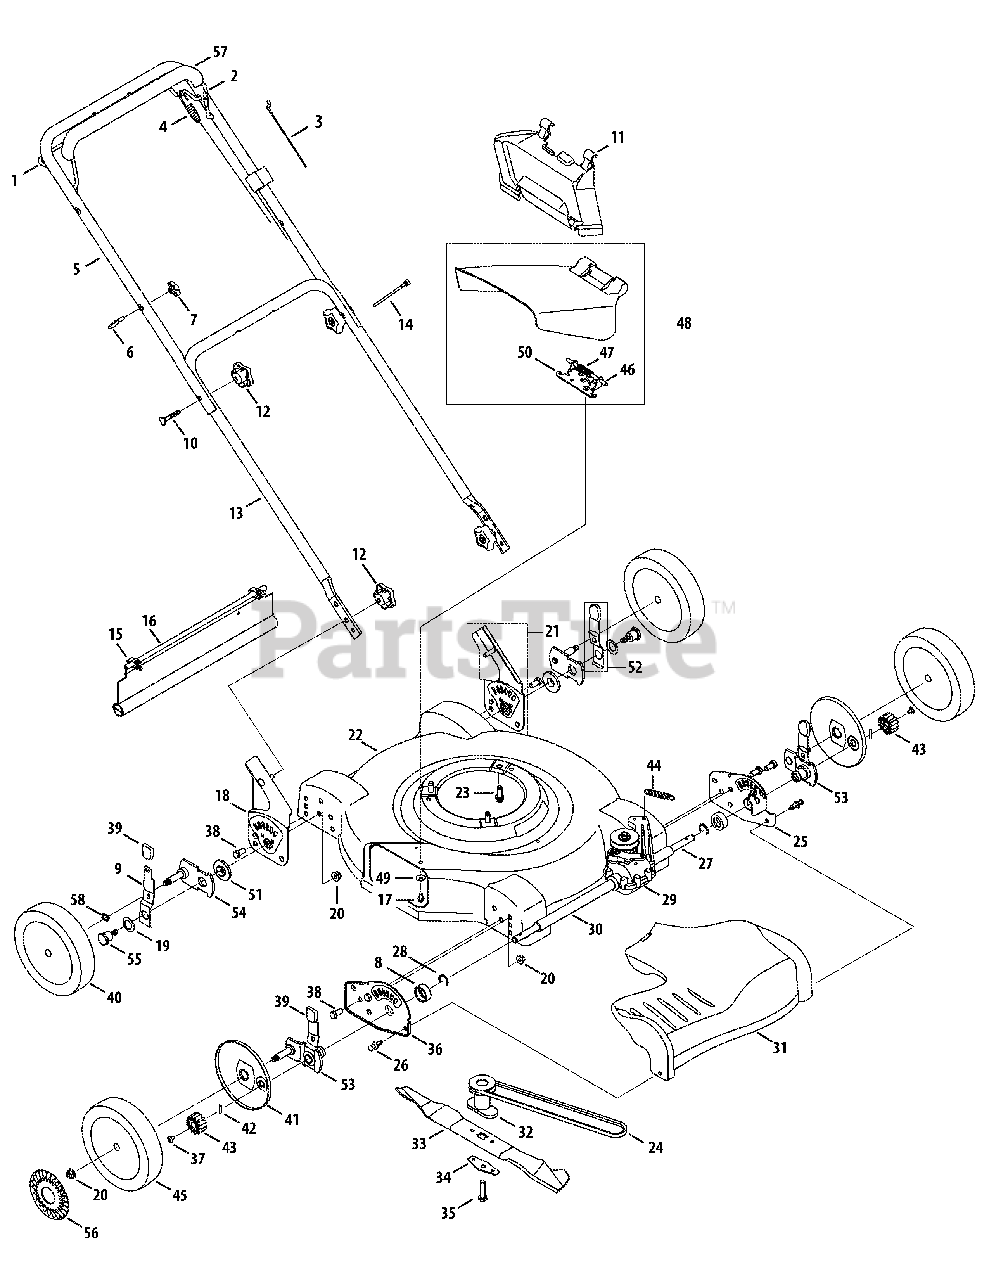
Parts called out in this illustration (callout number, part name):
1	Drive Control
3	Control Cable - 37.75''
3	Control Cable - 50.56''
4	Drive Control Cable
6	Eye Bolt
7	Wing Nut, 1/4-20
8	Bearing Support Spacer
9	Spring Lever
10	Carriage Bolt, 5/16-18 x 2.0
11	Mulching Baffle
12	Star Knob
14	Cable Tie
15	Hinge Clip
16	Trail Shield
17	Hex Screw, 1/4-20 x .500
20	Lock Nut, 3/8-16
23	Hex Washer Screw, 3/8-16 x 1.0
24	V-Belt, 3L x 32.90
26	Rivet
27	Sleeve Spacer, .550 ID x 2.22
28	Retainer Ring
29	Transmission Assembly Complete
30	Sleeve Spacer, .550 ID x 8.51
31	Transmission Cover
31	Transmission Cover - Yellow
32	Blade Adapter
33	22'' Mulching Blade
34	Blade Bell Support
35	Hex Cap Screw, 3/8-24 x 1.5
37	Screw, 1/4-20 x .390
38	Hex Cap Screw, 3/8-16 x .75
39	Adjustment Knob
40	Rear Wheel, 8 x 1.8, Bar
40	Rear Wheel, 8 x 1.8, Bar, Yellow
41	Wheel Dust Cover
42	Pin
43	Spur Gear 14T - RH
43	Spur Hear 14T - LH
44	Extension Spring, .47 OD x 2.50
45	Front Wheel, 8 x 1.8, Bar
45	Front Wheel, 8 x 1.8, Bar, Yellow
46	Hinge Pin
47	Torsion Spring
48	Side Discharge Assembly
49	Bell Washer, .265 ID x .75 OD
50	Deflector Chute Adapter
51	Height Adjustment Bearing
52	Rear Height Adjustment Lever
53	Front Lever Assembly
54	Rear Pivot Arm Assembly
55	Shoulder Screw, 3/8-16
56	Hub Cap
57	Deluxe Bail Cover
58	Wave Washer, .510 x .750 x .017
